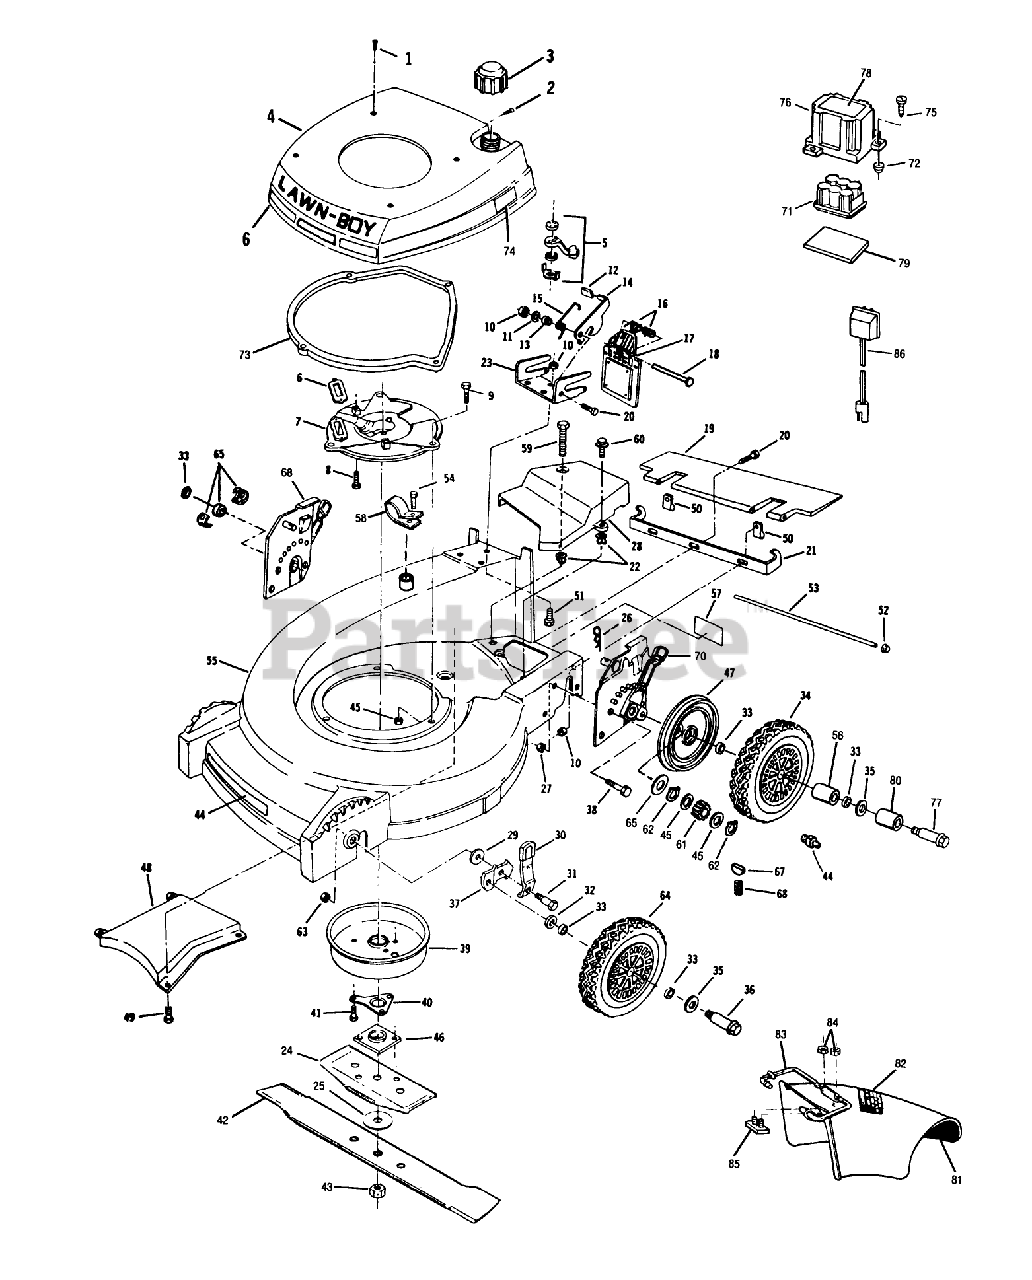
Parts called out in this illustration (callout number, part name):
1	SCREW LAWRENCE
2	SCREW S
3	FUEL CAP & INSERT
8	SCREW V
9	SCREW-HH
10	LOCKNUT E
12	KNOB (S&R)
15	SPRING
16	SPRING ASOC
18	ROD (RB&W)
19	T/SHIELD SM&P
25	WASHER
26	HAIR PIN
27	NUT-LOCK F
29	WASHER
30	SPRING ARM ASM
31	BOLT
32	WASHER WROUGHT
33	WASHER
35	SPACER
36	BOLT-SHOULDER
39	MUFFLER COVER F
40	SUPPORT F
41	SCREW
43	NUT-BLADE
44	FITTING LINCOLN
45	SPACER/GR ALGHNY
46	PLATE AND COLLAR ASM
48	BAFFLE CHUTE PL
54	SCREW LAWRENCE
60	SCREW
61	PINION BROCKWAY
62	RET RING
63	LOCKNUT
64	WHEEL&TIRE 8" TRI
65	THRUST WASHER
66	KEY
67	SPRING
69	REAR AXLE BEARING
72	NUT-CLIP
75	SCREW - SELF TAPPING
77	Screw
79	PAD-BATTERY
83	LATCH BAR ARGO
84	Nut
